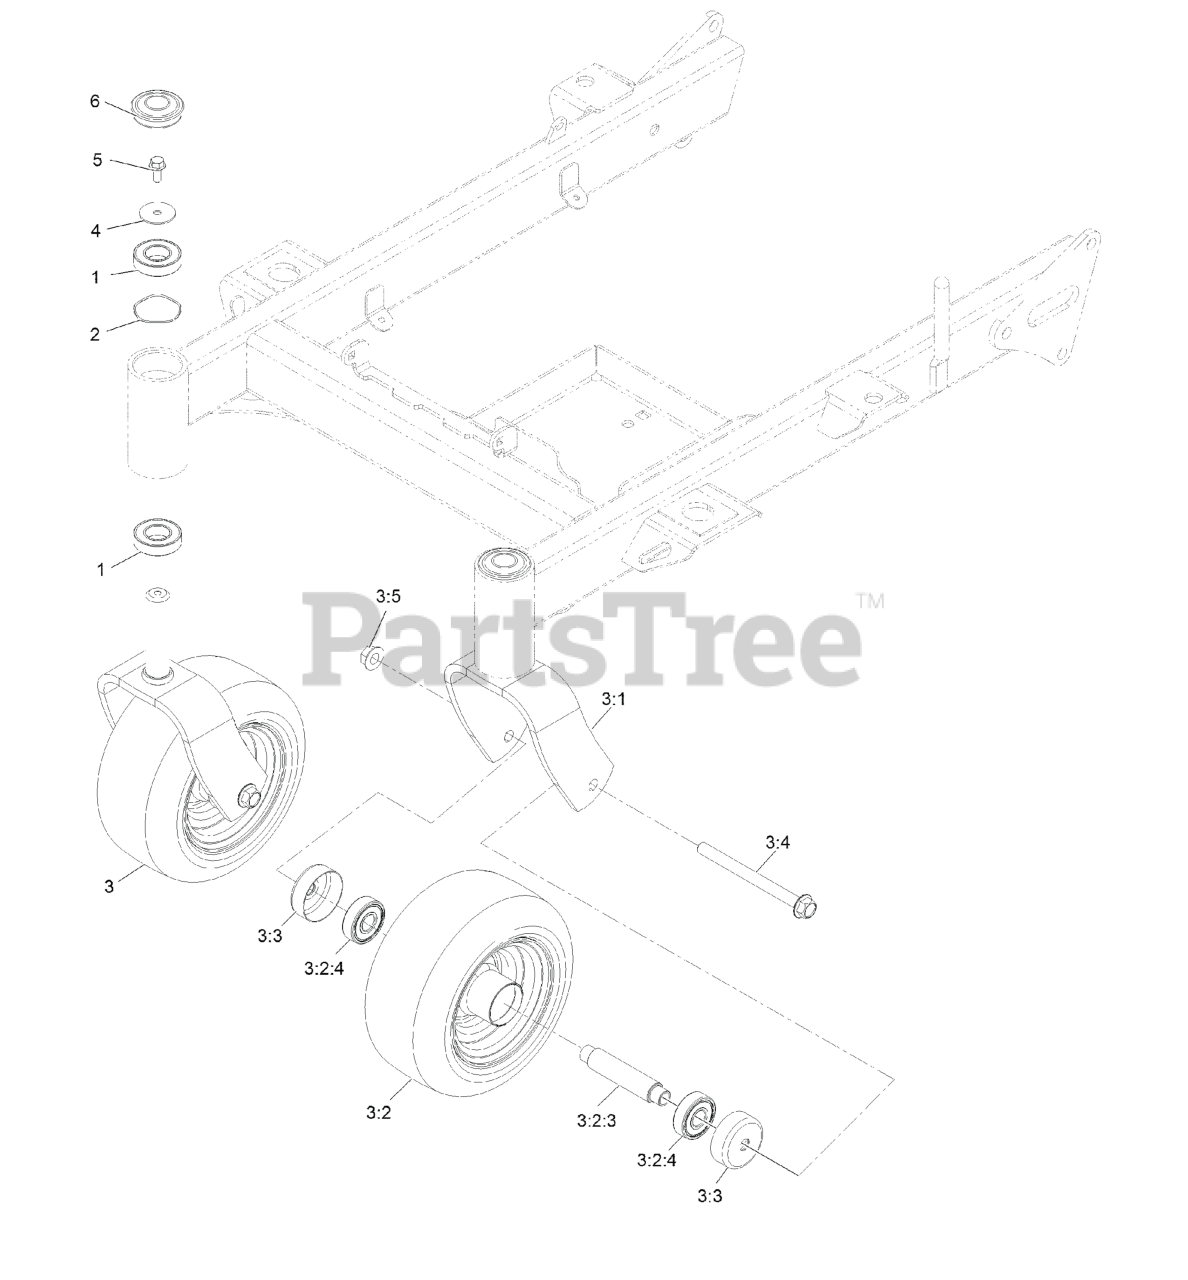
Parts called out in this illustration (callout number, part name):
1	BEARING-BALL
3	ASM-Caster Fork W/Tire
3:1	ASM-CASTER FORK
3:2	ASM-TIRE&WHL SP 9X4.50-5
3:2:3	AXLE-CASTER
3:2:4	BEARING
3:3	GUARD, SEAL
3:4	SCREW-HHF
4	WASHER-FLAT
5	SCREW-HHF
6	CAP-GREASE
